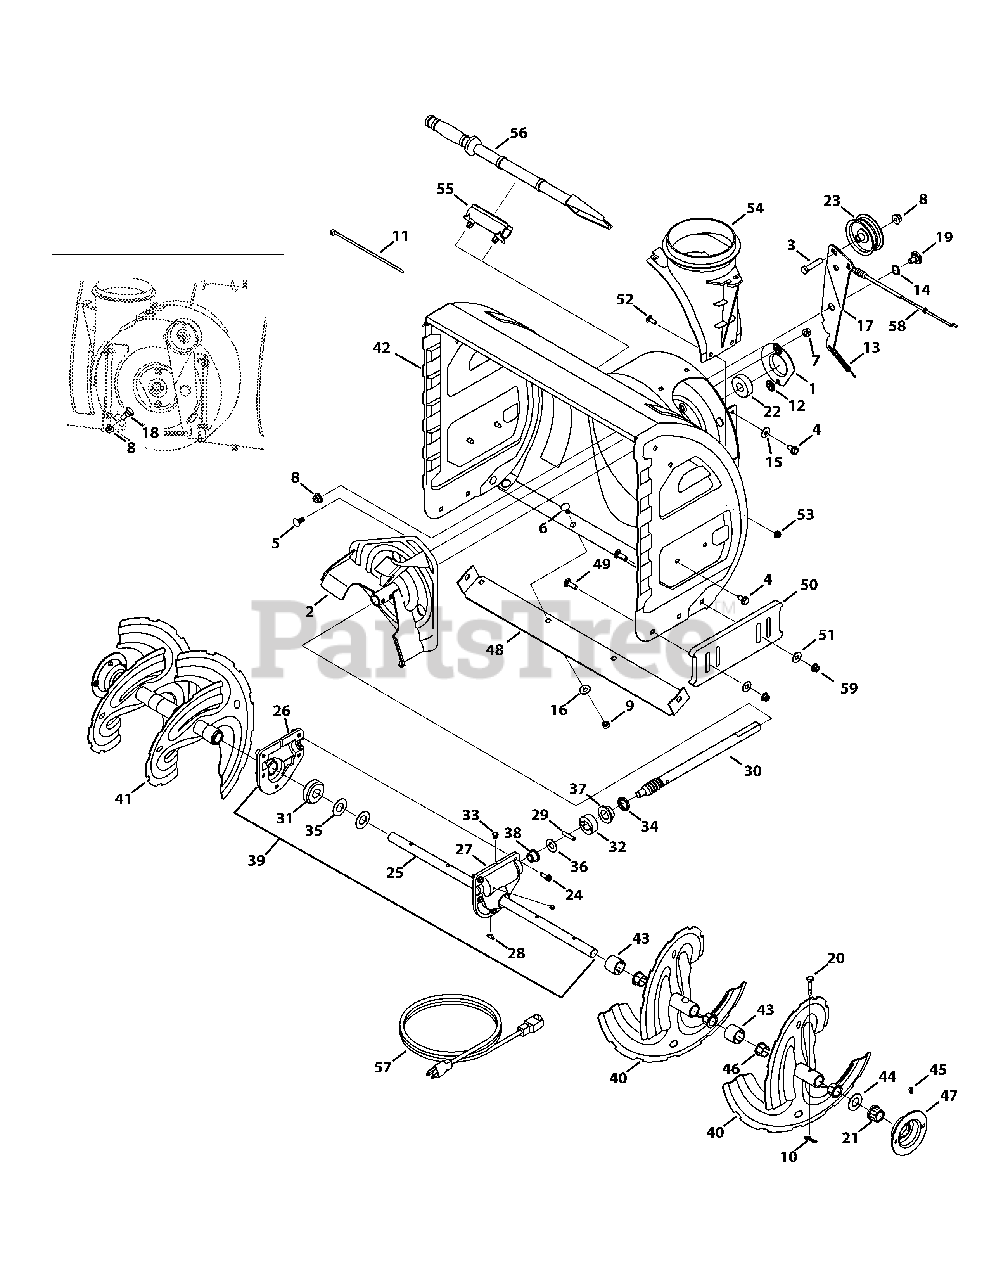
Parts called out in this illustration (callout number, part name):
1	Bearing Housing, 1.85 ID
2	Impeller Assembly, 12" Dia.
3	Hex Screw, 3/8-16 x 1.75
4	Taptite Screw, 5/16-18 x .750
5	Carriage Bolt, 5/16-18 x .75, Grade 5
6	Carriage Bolt, 5/16-18 x .750, Steel
7	Flange Lock Nut, 5/16-18
8	Flange Lock Nut, 3/8-16
9	Hex Nut, 5/16-18
10	Bow-Tie Cotter Pin
11	Cable Tie
12	Push-On Nut, .25 Dia.
13	Extension Spring, .38 OD x 4.59
14	Wave Washer, .625 x .885 x .0175
15	Washer, Bell, .340 x .872 x .060
16	Bell Washer, .340 x .872 x .06, Steel
17	Auger Idler Bracket
18	Shoulder Bolt, 3/8-16 x .496 x .336
19	Shoulder Screw, 3/8-16 x .625 x .17
20	Shear Pin, .25 x 1.50
21	Hex Flange Bearing x .75 ID
22	Flange Ball Bearing, .75 ID x 1.85 OD
23	Flat Pulley, 2.75 OD
24	Taptite Screw, 1/4-20 x .750
25	Auger Axle
26	Housing Assembly, RH
27	Housing Assembly, LH
28	Hi-Pro Key, 3/16 x 5/8
29	Dowel Pin, .25OD x 1.25
30	Worm Shaft, .75 OD
31	Worm Gear, 20T
32	Thrust Collar, .756 ID x .600
33	Plug, 1/4 x .437
34	Oil Seal, .75 x 1.131 x .188
35	Flat Washer, .760 ID x 1.50 OD
36	Flat Washer, .51 x 1.12 x .06
37	Flange Bearing, .75 ID x 1.0 OD x .59
38	Flange Bearing, .50 ID x .75 OD x .59
39	Gear Box; includes Ref. 24 - 38
40	Spiral Assembly (Left)
41	Spiral Assembly (Right)
42	Auger Housing, 24" Cub
43	Spacer, 1.25OD x .75ID x 1.00
44	Flat washer, .76 x 1.49 x .06
45	Drive Lube Fitting, 3/16
46	Flange Bushing, .800 ID x .910 OD
47	Bearing Housing
48	Shave Plate, 24"
49	Screw, Carriage, 5/16-18 x 1.00
50	Deluxe Polymer Skid Shoe - Blue
51	Washer, Flat, .349 x .879 x .063
52	Carriage Screw, 1/4-20 x .75
53	Flange Lock Nut, 1/4-20
54	Chute Adaptor, 5" Dia.
55	Cleanout Tool Mount
56	Cleanout Tool
57	Extension Cord
58	Auger Drive Cable
59	Hex Lock Nut, 5/16-18
